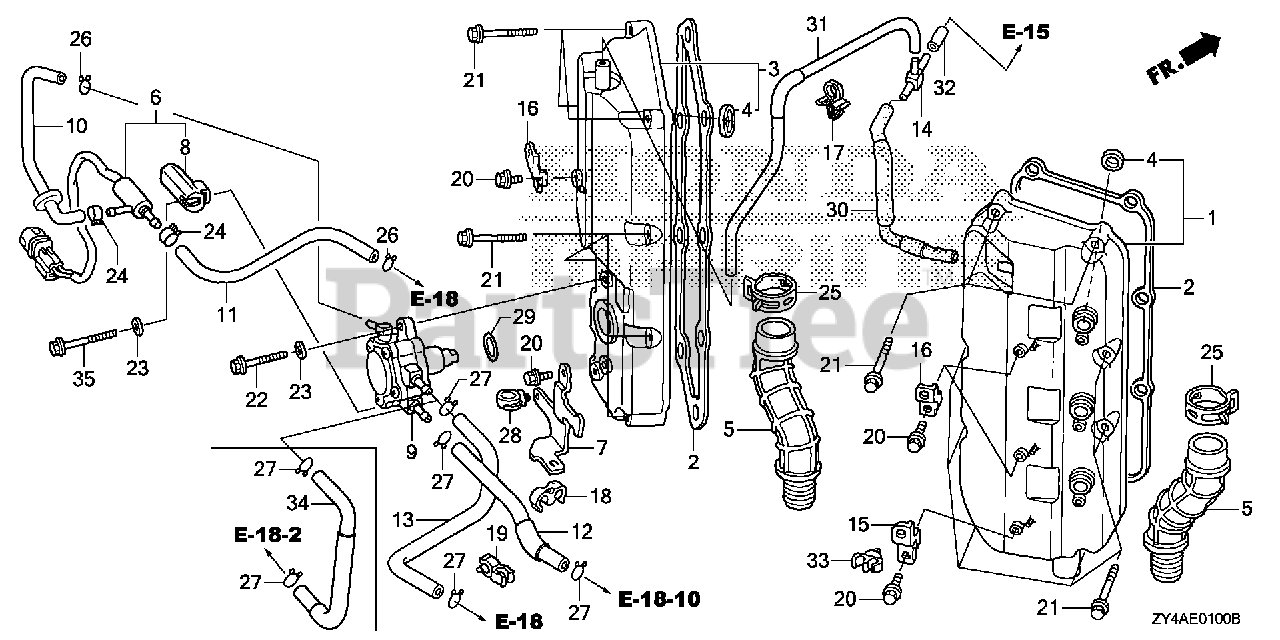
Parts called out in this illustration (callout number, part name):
1	COVER, R. CYLINDER HEAD *NH8* (DARK GRAY)
2	GASKET, HEAD COVER
3	COVER, L. CYLINDER HEAD *NH8* (DARK GRAY)
4	SEAL, SPARK PLUG TUBE (NOK)
5	TUBE, OIL
7	BRACKET, SOLENOID VALVE
9	PUMP ASSY., FUEL (MSDS)
12	TUBE G, FUEL
15	BRACKET, CLIP B
16	BRACKET C, HARNESS CLIP
17	CLIP A, WIRE
18	CLIP, SENSOR HOSE
19	CLIP, SHIFT WIRE
20	BOLT, FLANGE (6X14) (CT200)
21	BOLT, FLANGE (6X35)
22	BOLT, FLANGE (8X32)
23	WASHER, PLAIN (8MM)
25	CLAMP, TUBE (D32.5)
27	CLIP, TUBE (B12)
28	CLIP, HARNESS
29	O-RING (37X2.4) (ARAI)
30	TUBE A, BREATHER
31	TUBE B, BREATHER
32	TUBE C, BREATHER
33	CLIP D, WASHER TUBE
34	TUBE, FUEL (C)
35	BOLT, FLANGE (8X45)
